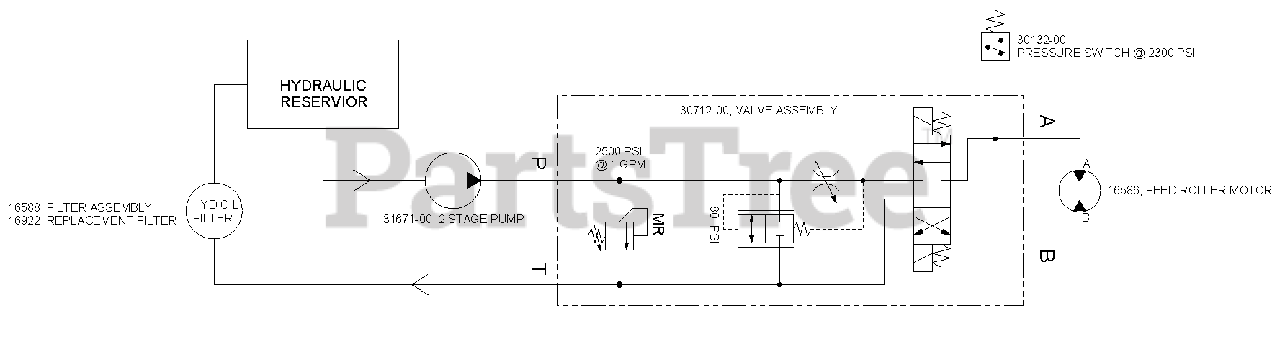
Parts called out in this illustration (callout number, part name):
1	BOLT, 3/8 X 2-1/4 HEX GR5 ZP
2	BUMPER, RUBBER
3	GRIP, 1.219 X 10.00
4	LATCH, RH HINGE
5	BOLT, 3/8 X 1" GR5 CRG NC ZP
6	BOLT, 3/8 X 1-1/2" GR5 CRG NC ZP
7	BOLT, 3/8 X 1-1/4 FLANGE NC
8	BOLT, 5/16 X 3/4 FLANGE NC
9	BOLT, 3/8 X 1 FLANGE NC
10	WASHER, 5/16" FLAT ZP
11	WASHER, 3/8" SAE FLAT ZP
12	WASHER, 3/4 INTERNAL LOCK
13	BOLT, 5/16 X 1" GR5 CRG ZP
14	BOLT, 5/16 X 3/4 GR5 CRG NC ZP
15	NUT, 3/8" NE NYLOCK ZP
16	BOLT, 5/16 X 1-1/4" GR5 CRG ZP
17	WASHER, 5/16" ID 7/8" OD NYLON FLAT
18	WASHER, 3/8" .062 TH NYLON FLAT
19	RIVET, AL BLIND 1/4 X 3/4 DOME HEAD
20	NUT, 5/16-18 NYLOCK-FLANGE
21	NUT, 3/8-16 NYLOCK FLANGE
22	PIN, 3/8" X 2-3/4" SNAP
23	SPRING, 1/2 X 2.00 LG ZP
24	CLAMP, CABLE MOUNT
25	DECAL, BEARCAT WEB
26	SENSOR, M18 PROXIMITY (REPLACEMENT PART)
27	SPACER, IDLER PIVOT
28	HINGE, EXTENSION TRAY
29	MOUNT, 5/8/9" DDC
30	MOUNT, 5/8/9" KNEEBAR PROX SENSOR
31	WELDMENT, INFEED TRAY
32	ASSEMBLY, DDC ENCLOSURE
33	WELDMENT, CHUTE SUPPORT
34	WELDMENT, 9" TOWABLE KNEE BAR
35	PLATE, 9" TOWABLE KNEE BAR
36	TUBE, 9" TOWABLE KNEE BAR HANDLE
37	LINK, PARALLEL
38	WELDMENT, KNEEBAR PIVOT
